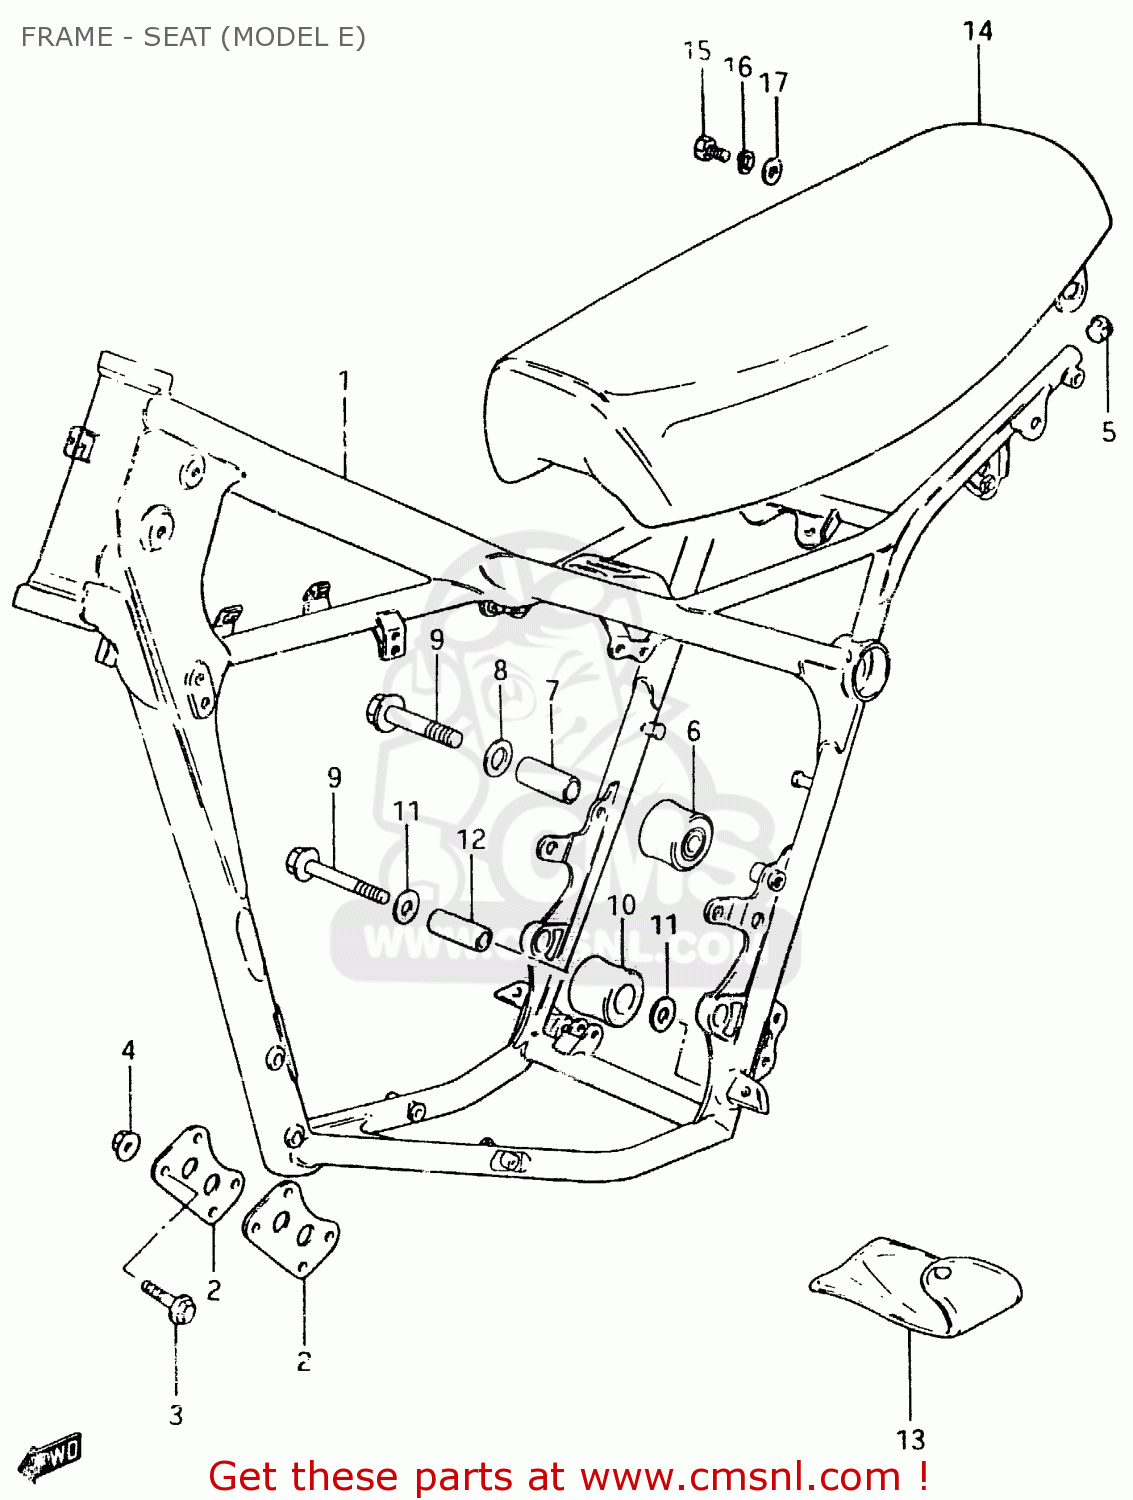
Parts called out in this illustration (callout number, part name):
1	FRAME
2	PLATE,ENGINE MOUNTING
3	BOLT(8X75)
4	NUT
5	PLUG(OD:17)
6	ROLLER,CHAIN
7	SPACER,CHAIN LENGTH ROLLER
8	WASHER
9	ROLLER,CHAIN LENGTH CONTROL
10	SPACER(8.6X12X25.5)
11	BOLT(8X45)
12	WASHER
13	TOOL SET
14	SEAT ASSEMBLY
15	BOLT
16	LOCK WASHER
17	WASHER
